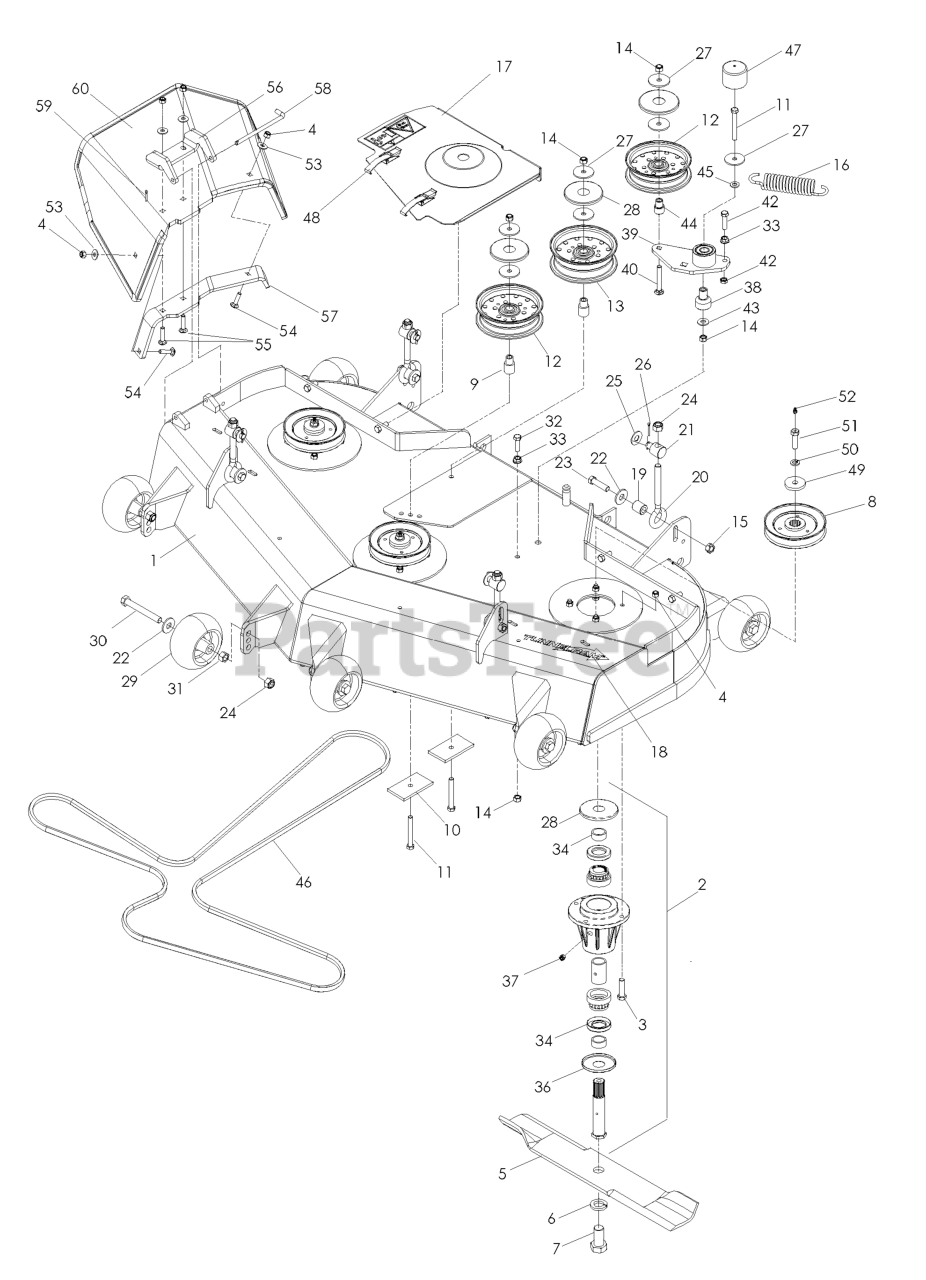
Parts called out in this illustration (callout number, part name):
1	DECK W/DECALS 52" HUS
2	HOUSING ASM, 52/61
3	HCS 5/16C X 1 1/4
4	NUT 5/16 NYLOC
5	BLADE OEM 18"
6	LOCKWASHER 5/8
7	HCS 5/8F X 1 1/4
8	PULLEY, 52
9	IDLER BUSHING
10	SUPPORT PLATE
11	HCS 3/8C X 3
12	IDLER PULLEY
13	IDLER PULLEY (TALL)
14	NUT 3/8-16 NYLOC
15	NUT 7/16C CENTERLOCK
17	52" BELT SHIELD ASM - RH
18	52" BELT SHIELD ASM - LH
19	DECAL, TUNNEL RAM 8"
23	WASH USS FLAT 1/2
24	HCS 7/16 - 14 X 1 3/4
25	NUT 1/2-13 HEX NYLOC ZD
26	WASHER 1/2 FLAT
27	PIN COTTER 1/8 X 1 ZD
28	WASHER, 3/8 SPEC
29	TOP DUST CAP
30	GAUGE WHEEL
31	HCS 1/2-13 X 4 GR 5 ZD
32	NUT HEX 1/2
33	HCS 3/8C X 1 1/4 GR5
34	NUT 3/8C WHIZ
35	SHAFT SEAL
36	BOTTOM DUST CAP
37	PLUG-VENTED
38	ZERK
39	PIVOT, BEARING
40	ARM-IDLER W/BRG
41	RHSNB 3/8-16 X 2.75
42	HCS 3/8-16 X 1-1/2
43	NUT 3/8-16 HEX JAM
44	WASHER 3/8 FLAT
45	BUSHING, IDLER
46	WASHER 3/8 SAE FLAT
47	PUMP BELT
48	CAP, VINYL
49	DRAW LATCH
50	SPINDLE WASHER
51	WASHER 7/16 LOCK
52	HCS 7/16-20 GD 8 SPEC
53	ZERK
54	WASHER 5/16 FLAT
55	BOLT, CARRIAGE 5/16X1-1/4
56	RHSNB 5/16-18 X 1-1/2 GR 5 ZD
57	PIVOT BRACKET - RUBBER CHUTE
58	BRACKET, REINF-CHUTE
59	PIN, CHUTE PIVOT
60	RP_COTTER PIN 1/8 X 3/4
61	CHUTE, RUBBER DISCHARGE 52/61"
